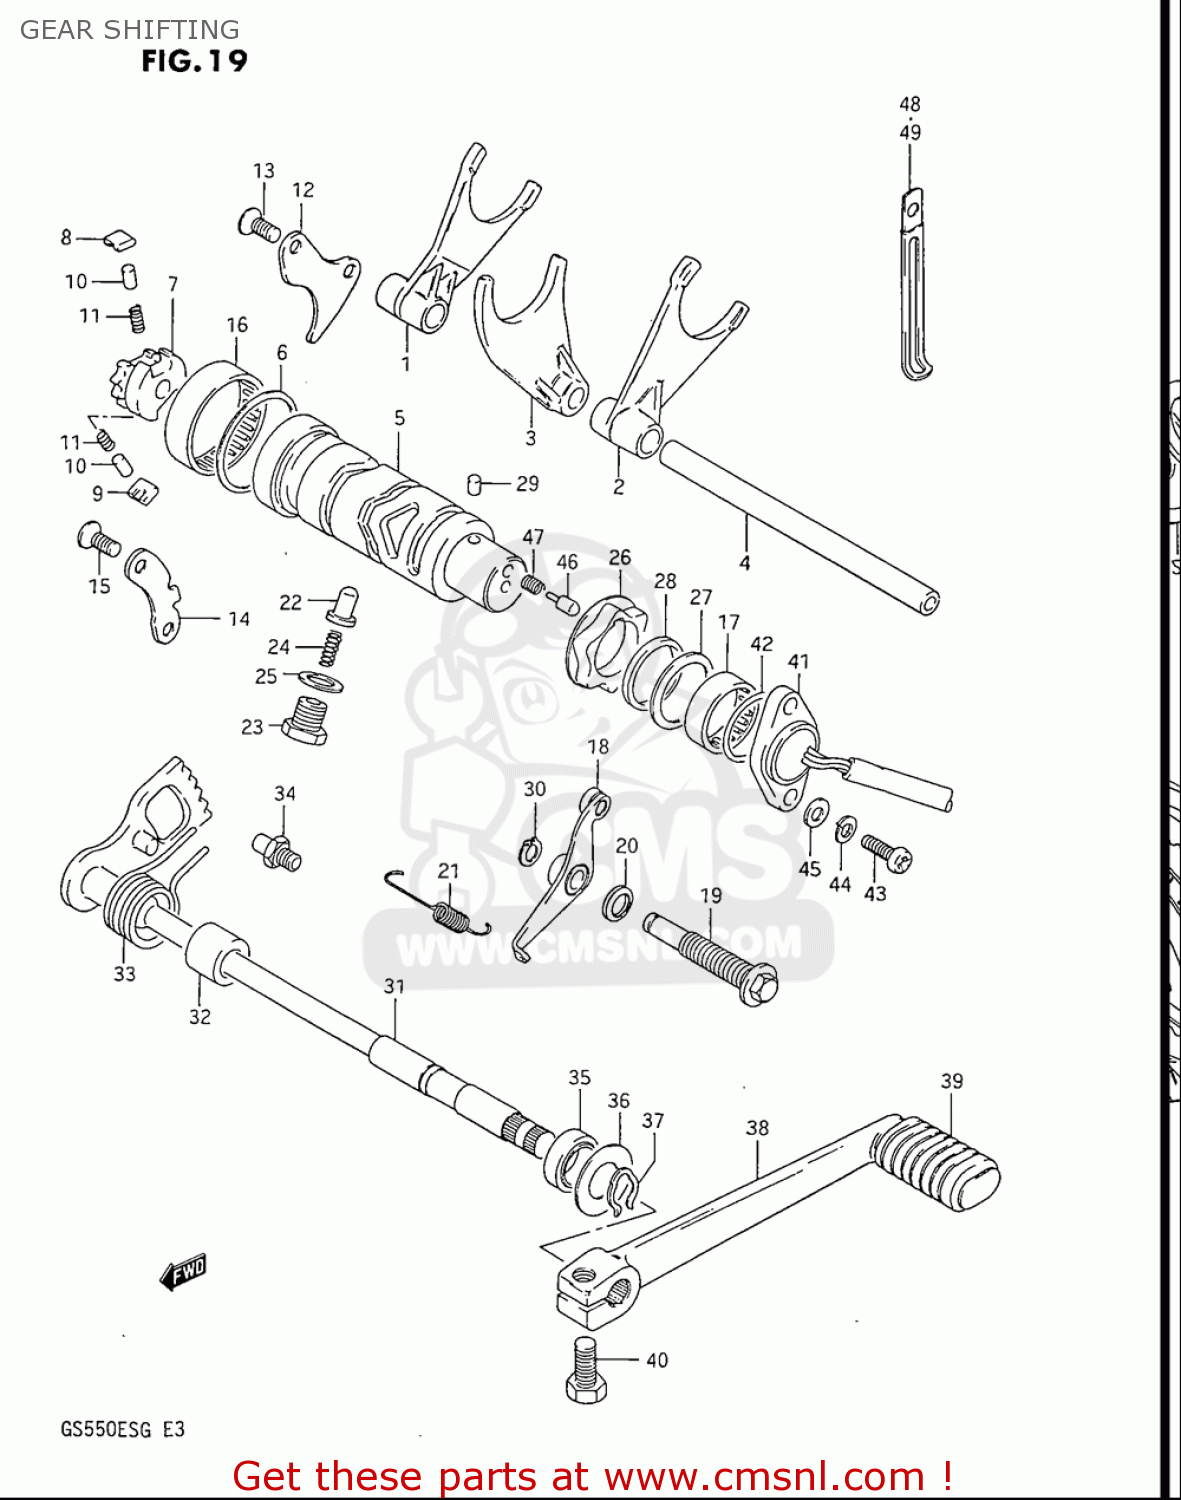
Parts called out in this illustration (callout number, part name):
2	FORK,GEAR SHIFT NO.2
7	GEAR,GEAR SHIFT CAM DRIVEN
8	PAWL,GEAR SHIFT NO.1
9	PAWL,GEAR SHIFT NO.2
10	PIN(5X8)
11	SPRING
12	LIFTER,GEAR SHIFT PAWL
13	SCREW
15	SCREW
16	BEARING(43X49X12)
17	BEARING(25X32X12)
20	GASKET(10X14X3.6) (NAS)
22	STOPPER,GEAR SHIFT CAM NO.2
23	HOLDER,GEAR SHIFT CAM STOP SPR
25	GASKET(14X19.2X2) (NAS)
26	PLATE,GEAR SHIFT CAM STOPPER
27	WASHER
29	PIN
30	CIRCLIP
32	SPACER(12X20X15.3)
33	SPRING
34	STOPPER,GEAR SHIFT ARM
35	SEAL,OIL (12X22X9)
36	WASHER (12.5X26X1.6)
37	CIRCLIP,12 MM
38	LEVER ASSY,GEAR SHIFT
39	RUBBER,PEDAL
40	BOLT
42	O RING(D:2.4,ID:26.2)
43	SCREW(5X14)
44	WASHER,LOCK
45	WASHER
46	PIN(5X15.5)
47	SPRING
48	CLAMP(L:65)
49	CLAMP(L:80 T:1.0)
